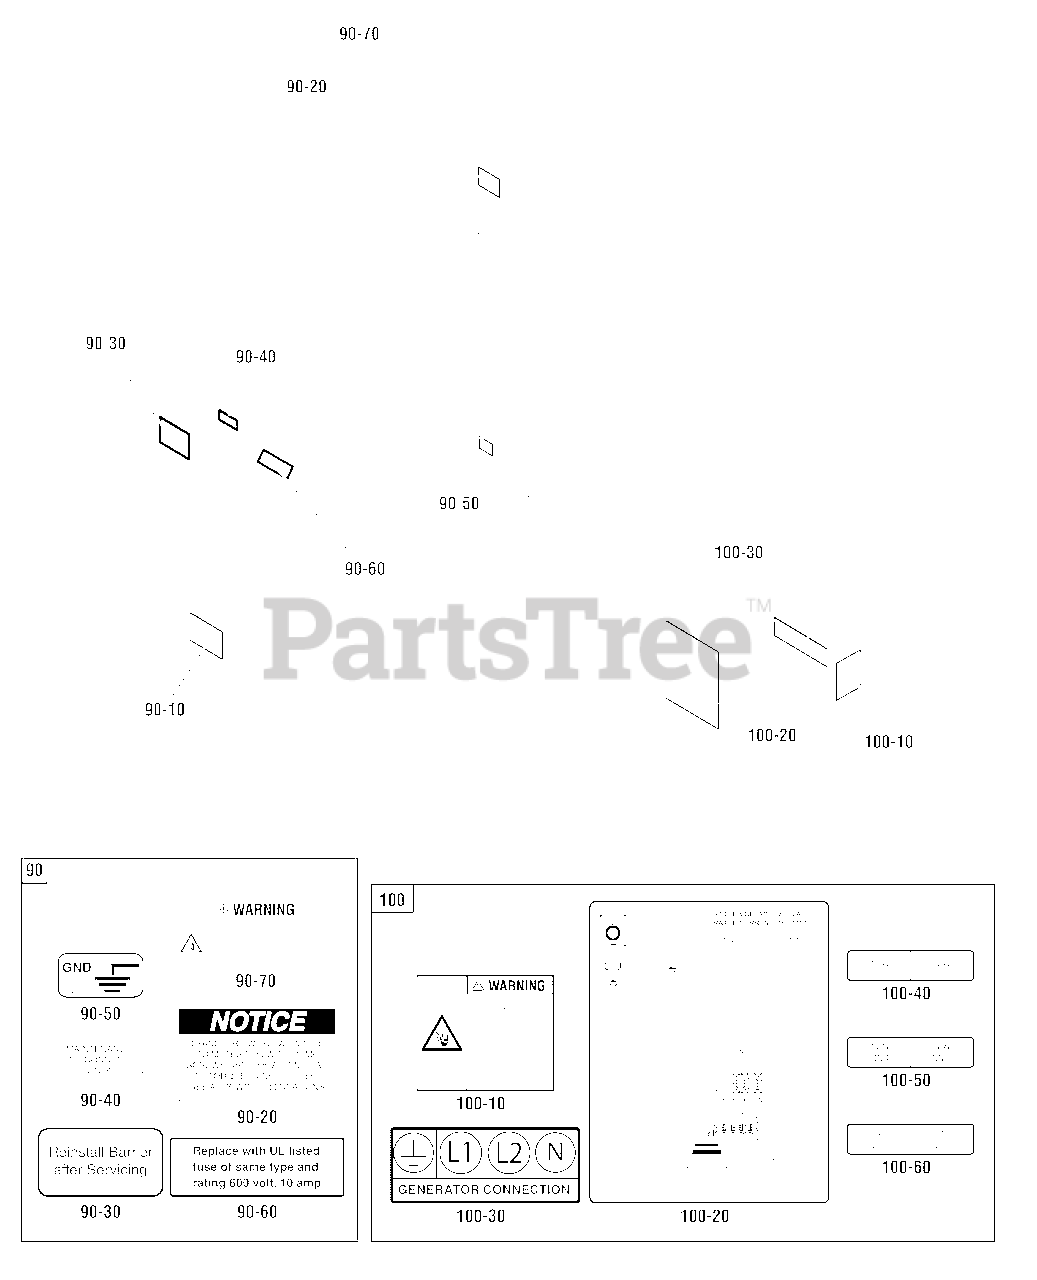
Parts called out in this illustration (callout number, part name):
90	DECAL SHEET, Warnings
90-20	DECAL, Notice, Install Torque
90-30	DECAL, Reinstall Barrier
90-40	DECAL, Maintenance Switch Disconnect
90-50	DECAL, Ground
90-60	DECAL, Fuse
90-70	DECAL, Warning, Electric Shock
100	DECAL SHEET, Warnings, Junction Box
100-10	DECAL, Warning, Hazardous Voltage
100-20	DECAL, Junction Box
100-30	DECAL, GND/L1/L2/N
100-40	DECAL, TXRX
100-50	DECAL, TXRX, GND
100-60	DECAL, 240 VAC
